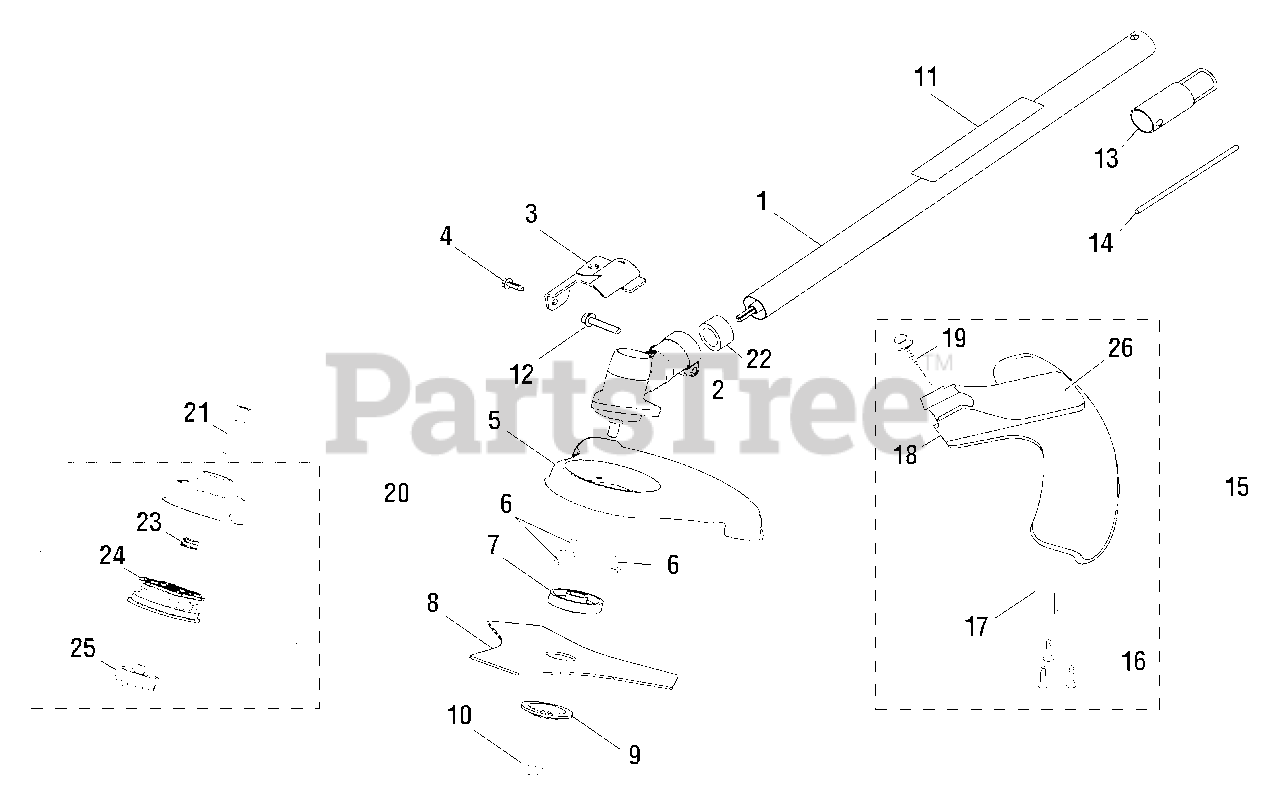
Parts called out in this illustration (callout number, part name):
1	STRAIGHT SHAFT ASSEMBLY
2	GEAR CASE ASSEMBLY
3	GRASS DEFLECTOR CLAMP
4	SCREW (#10-24 X 5/8 in. HEX WASHER HD.)
5	BLADE GUARD
6	SCREW (#10-24 X 1/2 in. SLOTTED HEX HD.)
7	FLANGED WASHER
8	BLADE (TRI-ARC™)
9	CUPPED WASHER
10	BLADE NUT, LEFT-HANDED THREADS
11	WARNING LABEL
12	SCREW (1/4-20 X 1-1/4 in.)
13	HANGER CAP
14	HEAD LOCKING TOOL
15	GRASS DEFLECTOR ASSEMBLY
17	LINE CUTTING BLADE
18	GRASS DEFLECTOR
19	SCREW (#1/4-20 X 1-1/4 in. HEX WASHER HD.)
20	TRIMMER HEAD ASSEMBLY (.095)
21	TRIMMER HEAD SHAFT ADAPTOR
23	COMPRESSION SPRING
24	SPOOL WITH LINE (.095)
25	RETAINING CAP, LEFT-HANDED THREAD
26	GRASS DEFLECTOR LABEL
